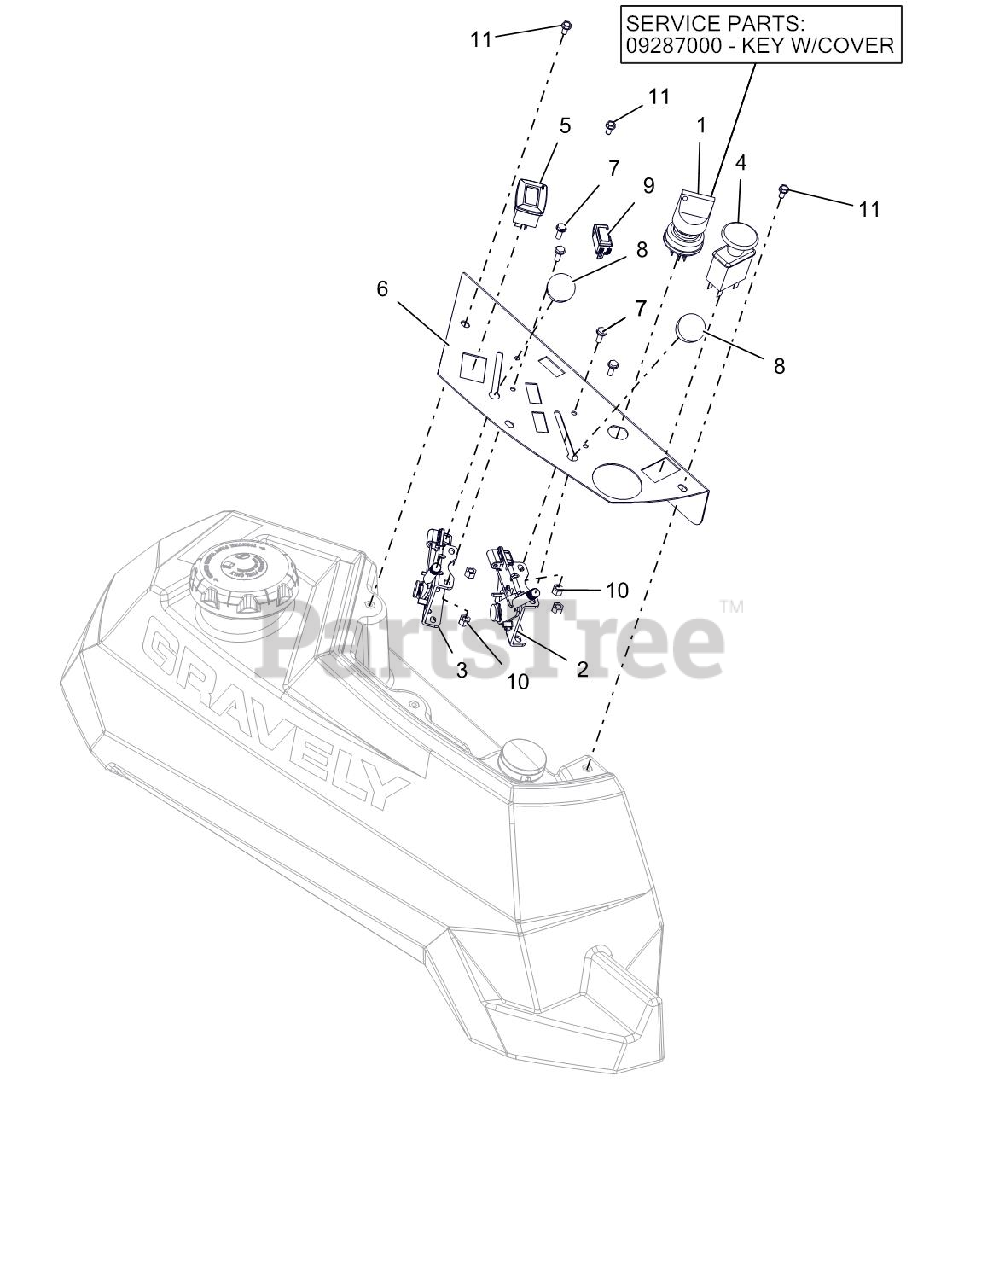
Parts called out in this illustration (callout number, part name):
1	KEY, W/ SHIELD
1	SWITCH, IGNITION
2	CABLE, PRO-CONTROL 28.50
3	CABLE, PRO-CONTROL 31.50"
4	SWITCH, CLUTCH
5	METER, HOUR W/MAINTENANCE
6	PT100 CONTROL PANEL - RED
7	@SCR-MCH 10-24X.50 HWH YWZC
8	KNOB-CONTROL-BLACK .38-16X.50
9	LIGHT,INDICATOR
10	@NUT-LK-NYL 10-24 W/INSRT YWZC
11	SCR-MCH 10-24X.38 HWHSTAINLESS
